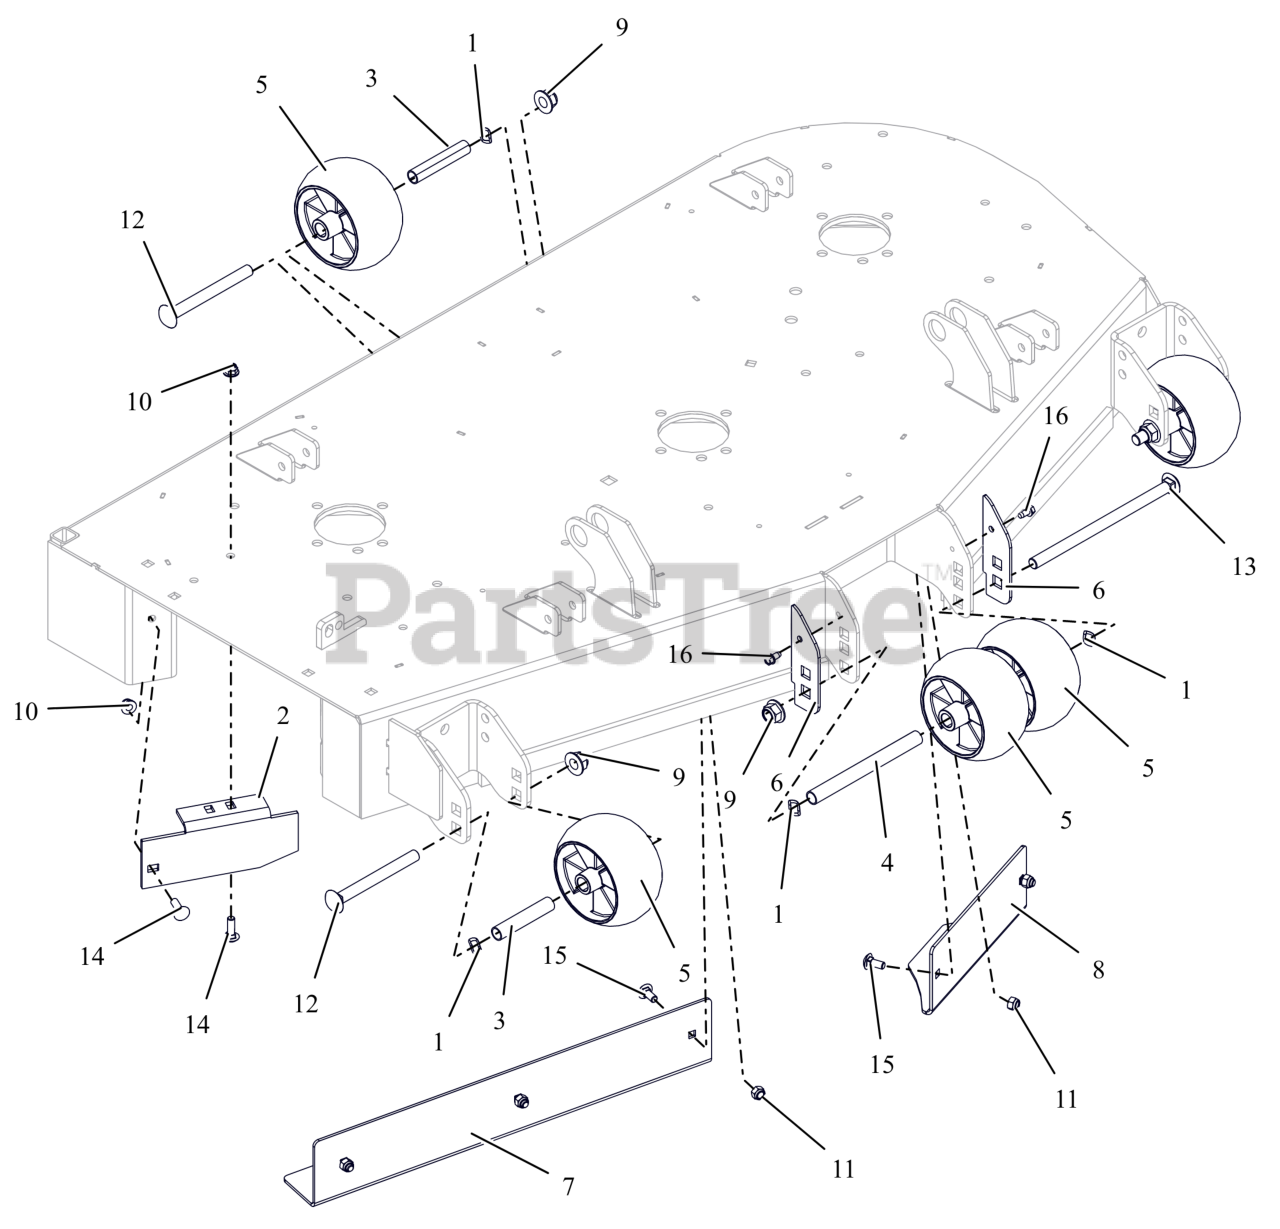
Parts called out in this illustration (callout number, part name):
1	WAVE WASHER .531X.781X.125FH
2	BAFFLE, 44/48" SIDE DISCHARGE
3	SPACER, .510X.625X3.35
4	SPACER, .510X.625X6.50
5	ANTI-SCALP WHEEL - 5X3 CTR
6	PLATE, ANTI SCALP WHEEL EXT.CE
7	BAFFLE, 48" RH VACUUM (ORANGE)
8	BAFFLE, 44/48" LH VACUUM (ORANGE)
9	NUT,NYL-FLG .50-13 GF ZCC
10	NUT,LK-NYL-FLG .31-18 G5ZC120
11	NUT,NYL .31-18 G5 ZCC
12	BLT, RHSN .50-13X5.00 G5 ZCC
13	BLT, RHSN .50-13X8.50 G5 ZCC
14	BLT,RHSN .31-18X1.00 G5 ZCC
15	BLT,RHSN .31-18X.75 G5 ZCC
16	SCR-TAP .25-20X.50 HWH ZCC
